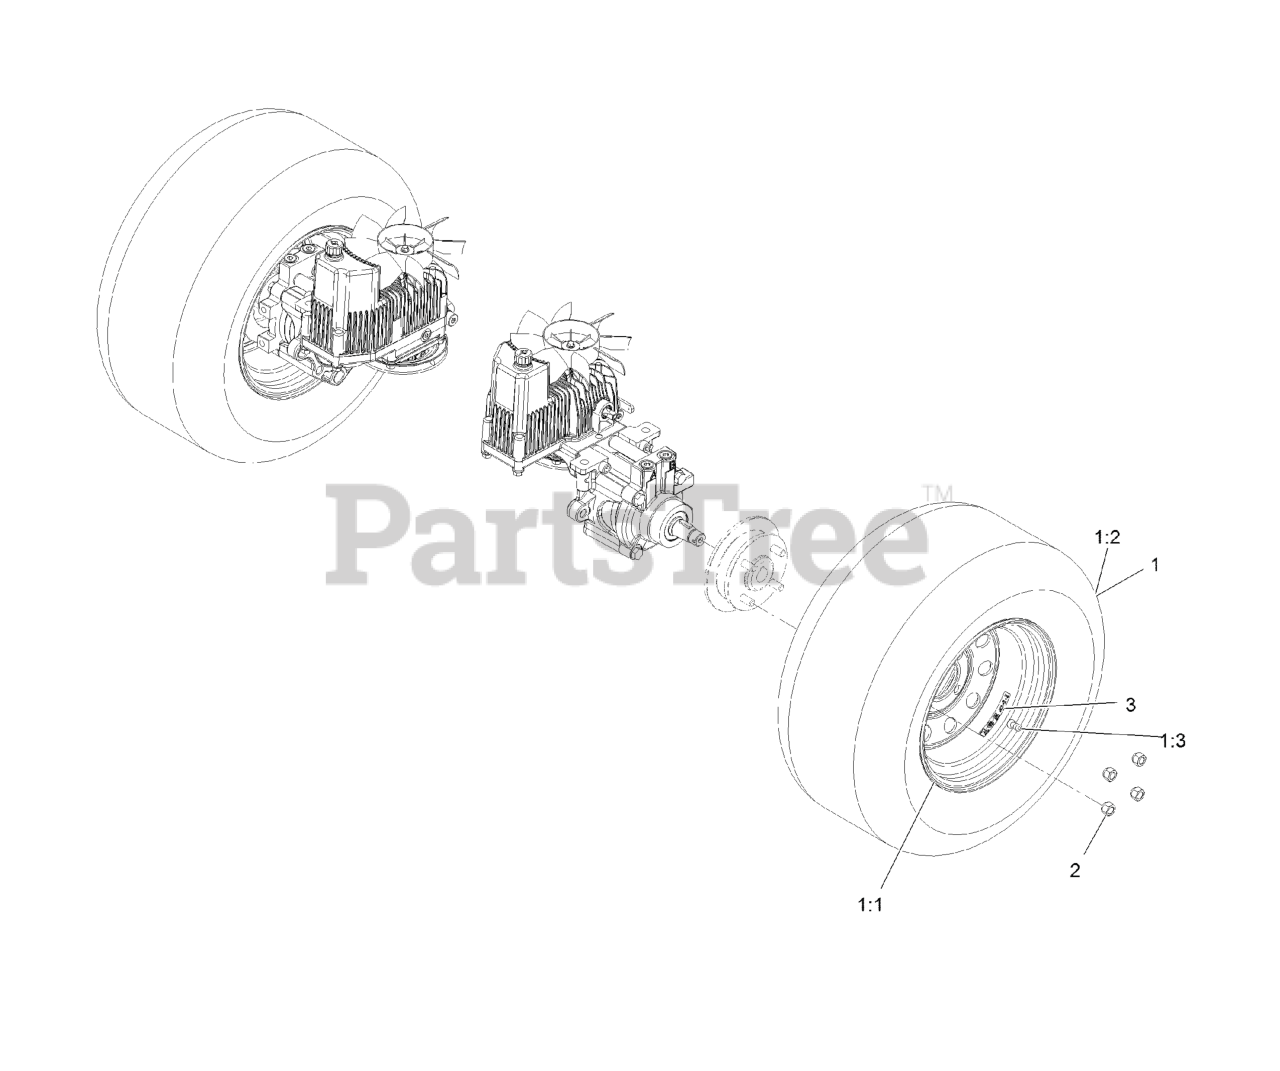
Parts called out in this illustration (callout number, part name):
1	ASM-WHEEL AND TIRE
1:1	ASM-RIM 60
1:2	TIRE-DRIVE
1:3	Stem-Valve
2	NUT-LUG
3	DECAL-TORQUE, WHEEL HUB LUG
